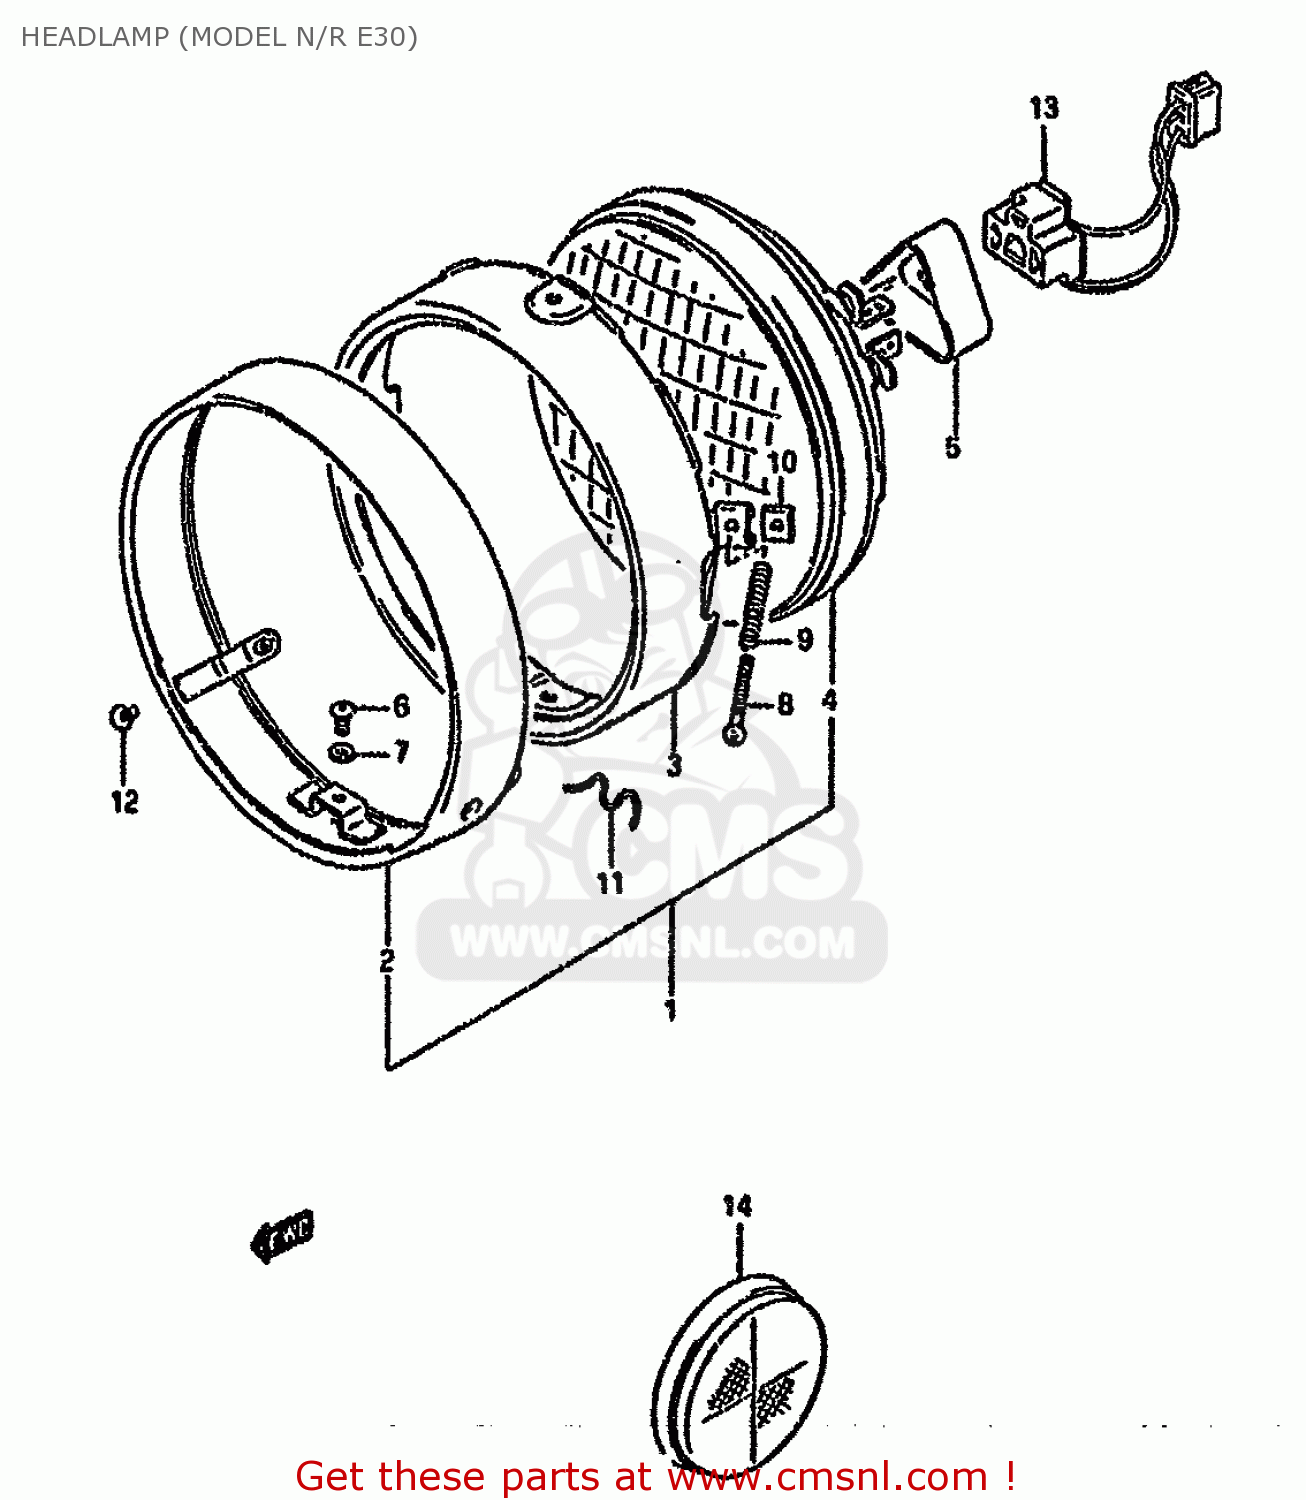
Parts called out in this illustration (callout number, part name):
1	LAMP ASSEMBLY,HEAD
2	RIM
3	RETAINER
4	LAMP UNIT
5	COVER
6	SCREW
7	LOCK WASHER
8	SCREW
9	SPRING
10	NUT
11	SPRING,HEAD LAMP UNIT
12	SCREW
13	LEAD WIRE,HEADLAMP
14	REFLEX REFLECTOR,RR
16	SCREW(5X12)
17	WASHER
18	SCREW
